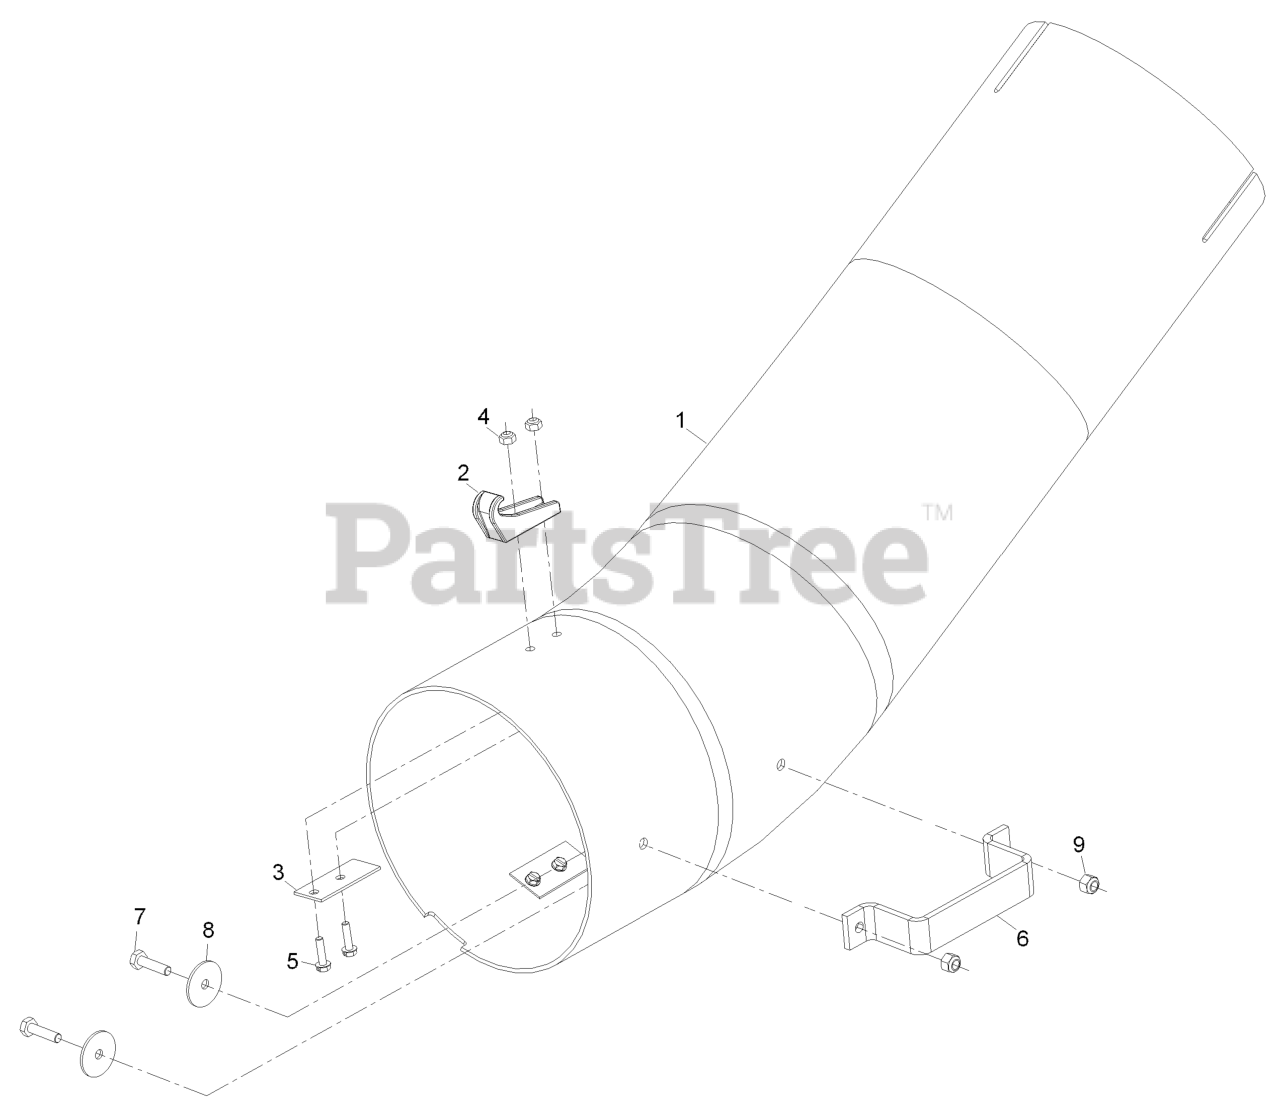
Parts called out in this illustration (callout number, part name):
1	TUBE-LOWER
2	LATCH-CATCH
3	PLATE-BACKING
4	NUT-LOCK, NI
5	SCREW-HWH
7	SCREW-HH
8	WASHER-FLAT
9	NUT-LOCK, NI
